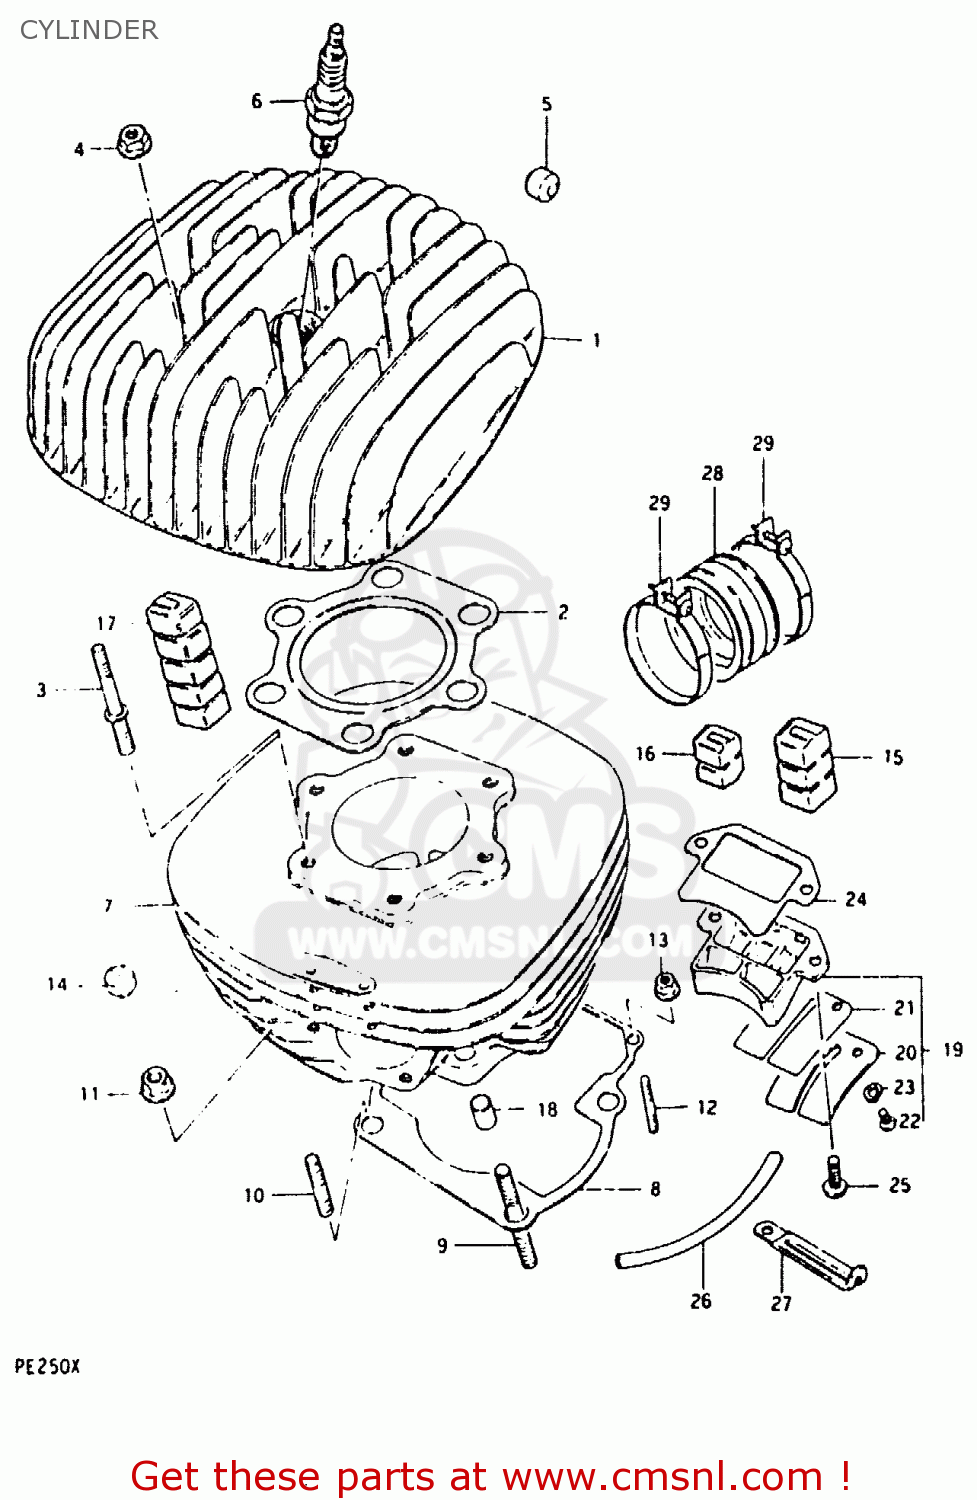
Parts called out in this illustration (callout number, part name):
1	HEAD,CYLINDER
2	GASKET,CYLINDER HEAD (NAS)
3	BOLT,STUD
4	NUT
5	PAD,CYLINDER HEAD
6	SPARK PLUG (NGK, BR10EV)
7	CYLINDER
8	GASKET,CYLINDER (MCA)
9	STUD BOLT (L:40)
10	STUD 10X25
11	NUT
12	STUD 6X20
13	NUT
14	PAD,CYLINDER HEAD
15	PAD,CYLINDER
16	PAD,CYLINDER
17	PAD,CYLINDER
18	PIN
19	VALVE ASSEMBLY,REED
20	STOPPER,REED VALVE
21	VALVE,REED
22	SCREW
23	LOCK WASHER
24	GASKET,REED VALVE (MCA)
25	SCREW
26	HOSE
27	CLAMP
28	PIPE,INTAKE
29	CLAMP
